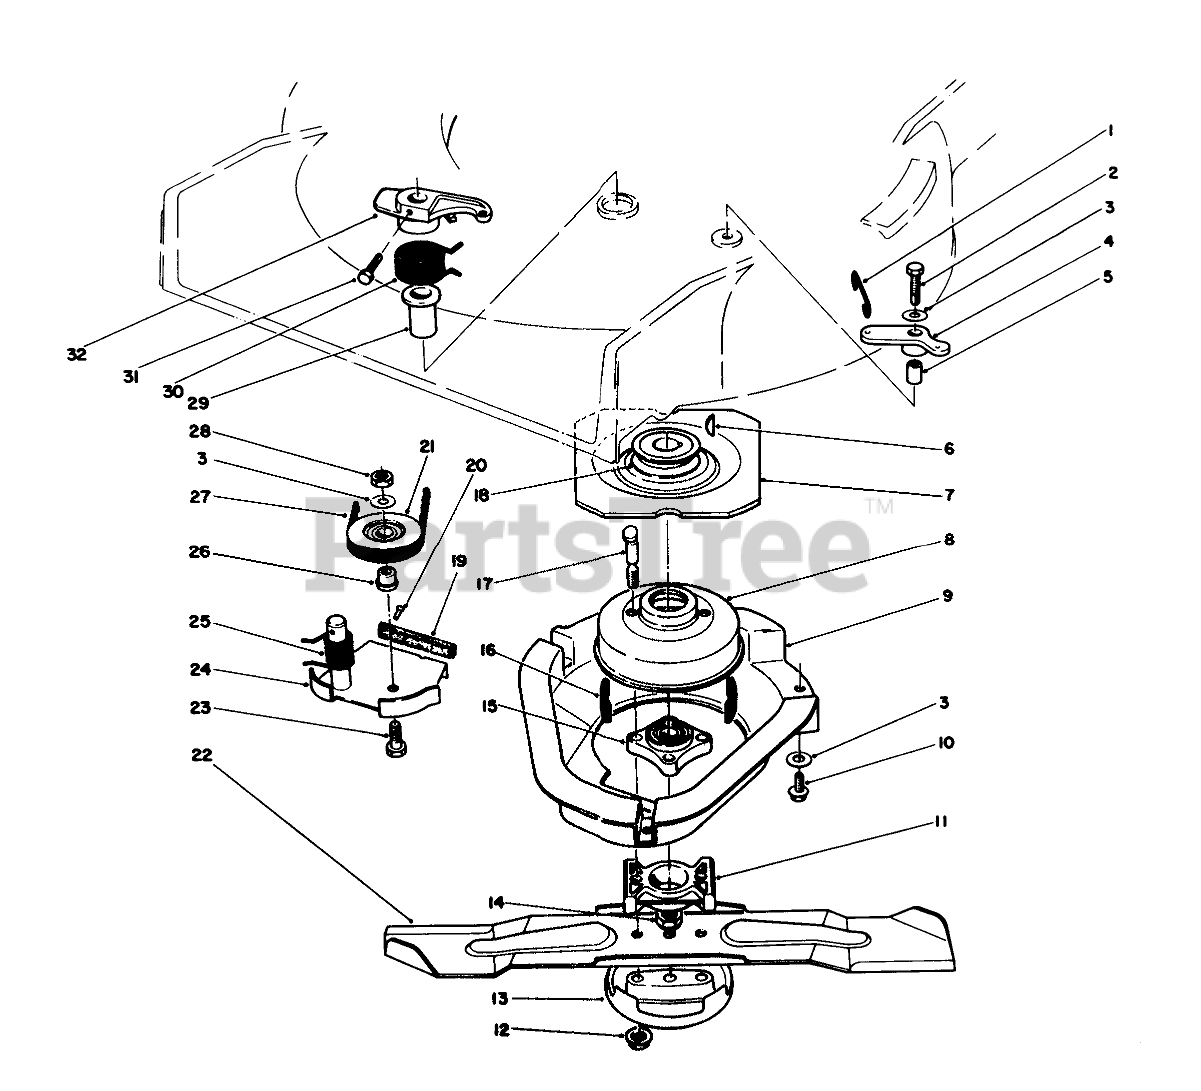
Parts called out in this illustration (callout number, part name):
1	LINK-CONTROL
2	SCREW-HH
3	WASHER-PLAIN
4	BELLCRANK
5	SLEEVE-BELLCRANK
6	KEY-WOODRUFF
7	Flywheel
8	Drum-Brake
9	SHIELD BBC
10	SCREW-HWHTF
11	SPACER-BLADE
12	NUT-LOCK
13	Anti Scalp Cup
14	NUT-LOCK, NI
15	HUB ASM
16	DAMPENER-VIBRATION
17	BOLT-BLADE
18	PULLEY
19	Pad-Brake
20	.185 DIA X .375 RT +
21	PULLEY-IDLER
22	BLADE-21in
23	SCREW-HH
24	Brake Plate (Incl. Ref. #19 & 20)
25	SPRING-TORSION
26	HUB-PULLEY, IDLER
27	V-BELT
28	NUT-LOCK, NI
29	BUSHING PM
30	SPRING-TORSION
31	SCREW-HH
32	LEVER
